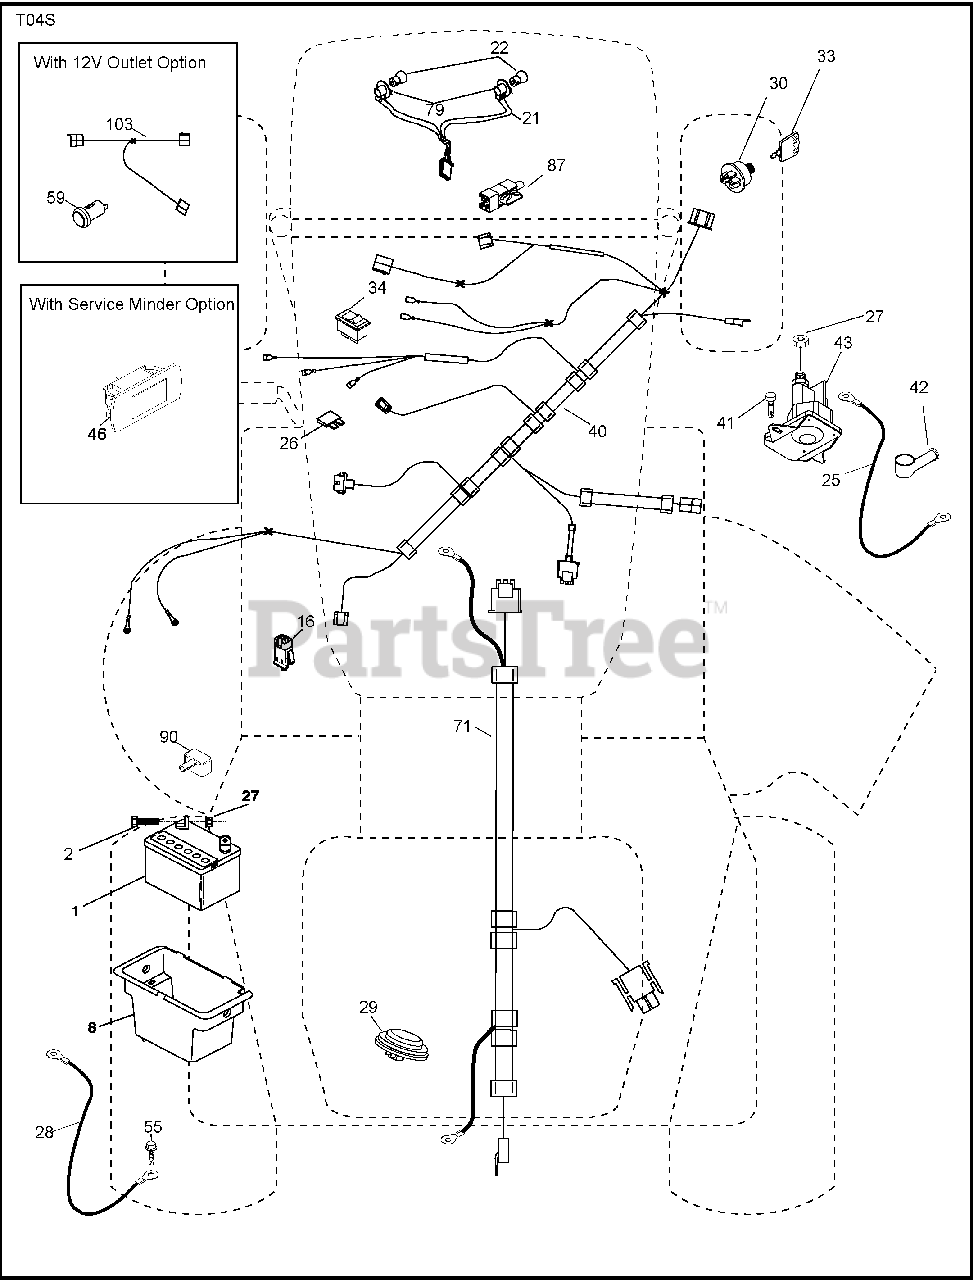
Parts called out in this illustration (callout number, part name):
1	Battery
2	Bolt Hex Head 1/4-20 x 3/4
8	Box Battery
16	Switch Interlock Push-In
21	Harness Socket Light w/4152J
22	Bulb Light
25	Cable Starter
26	Fuse
27	Nut Keps Hex 1/4-20 unc
28	Cable, Ground
29	Switch, Seat
30	Switch, Ignition
33	Key/Chain
34	Switch Light/Reset
40	Harness Ignition Dash
41	Screw Thd Cut 1/4-20 x 1/2
42	Cover, Terminal
43	Solenoid
46	Gauge SRVCMNDR HRMTR
55	Screw Thdrol 5/16-18 x 3/4 TYTT
71	Harness Ignition
79	Socket Asm Bulb Twistlock
87	Switch Interlock Clutch Cable
90	Cover Terminal Battery
141	Kit T2 ROS
